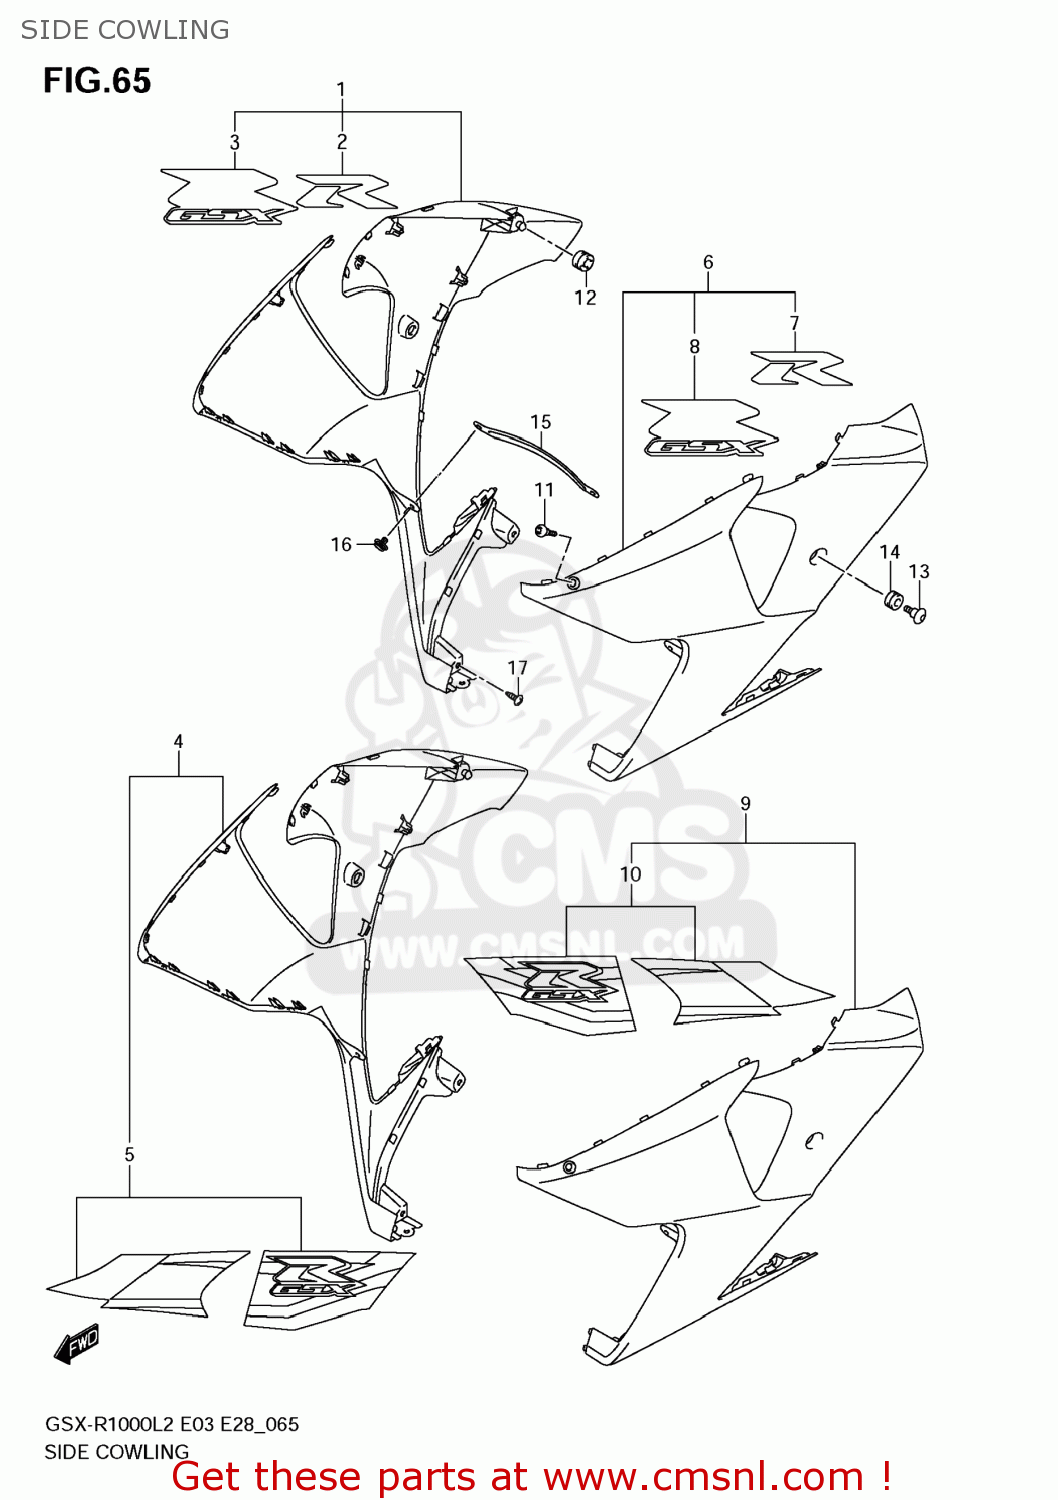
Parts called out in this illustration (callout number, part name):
1	COWLING,SIDE,R(BLACK)
2	EMBLEM,R
3	EMBLEM,GSXR,R
4	COWLING,SIDE,R(BLUE)
5	TAPE SET,SIDE COWLING,R
6	COWLING,SIDE,L(BLACK)
7	EMBLEM,R
8	EMBLEM,GSXR,L
9	COWLING,SIDE,L(BLUE)
10	TAPE SET,SIDE COWLING,L
11	SCREW(5X16)
12	CUSHION
13	SCREW(6X20)
14	CUSHION
15	BRACKET,UNDER COWLING CTR
16	CLIP
17	SCREW
